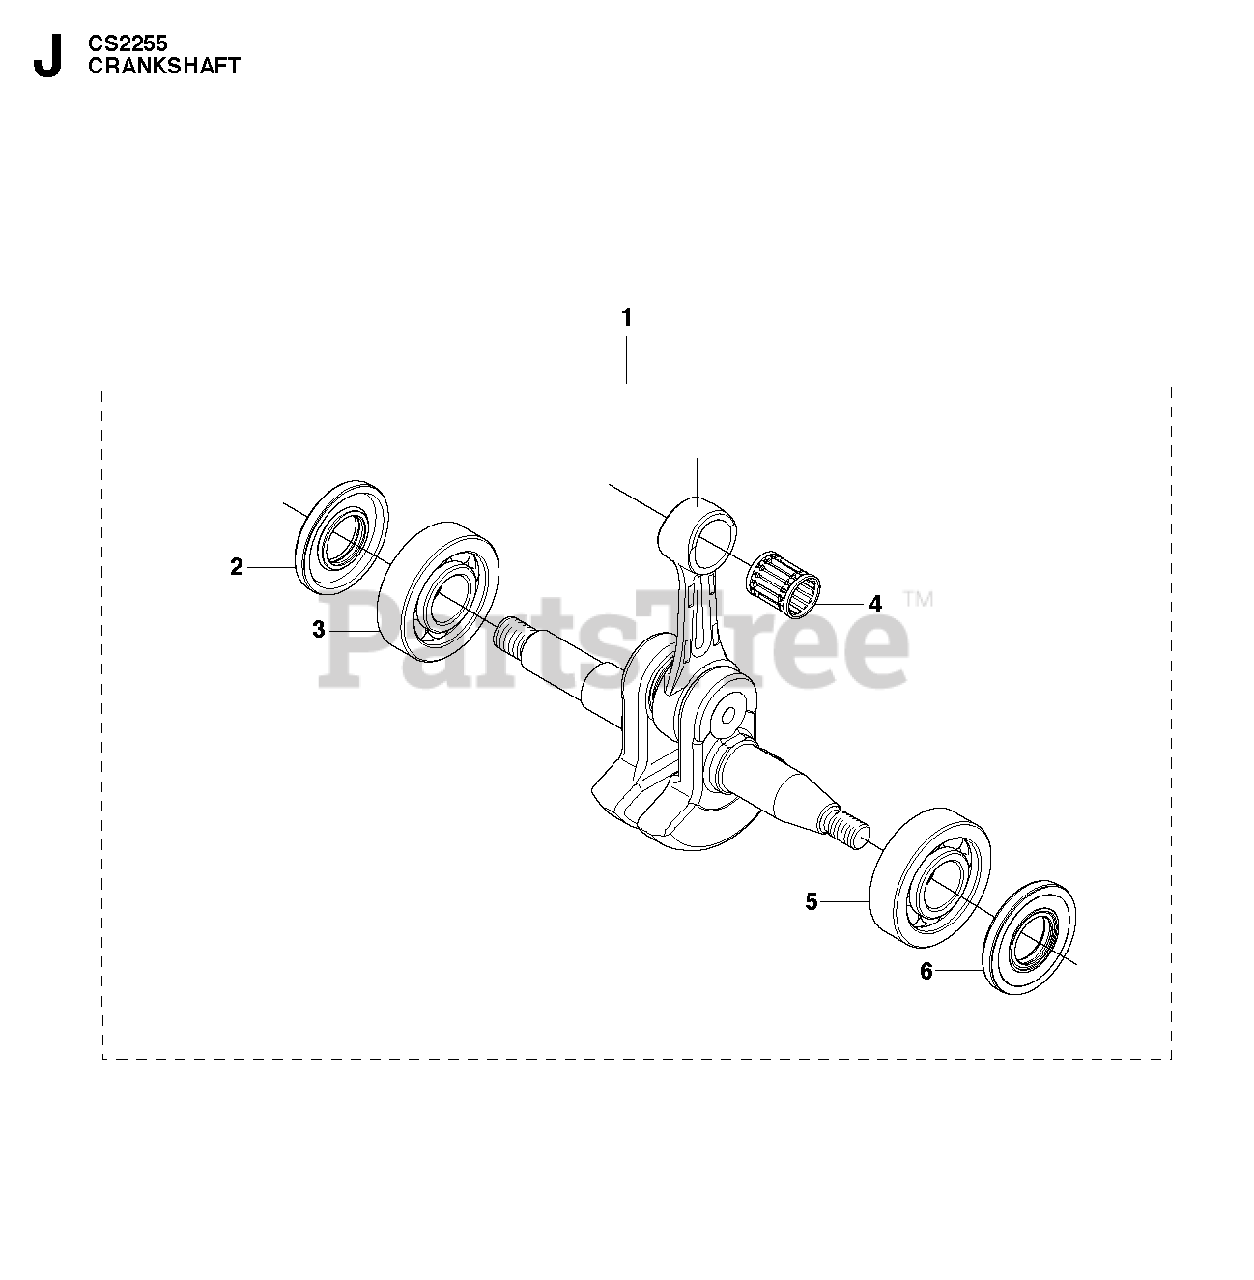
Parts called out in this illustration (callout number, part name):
1	RP CRANKSHAFT CPL
2	COVER
3	BEARING
4	SUPPORT BUSHING
5	BEARING
6	COVER
